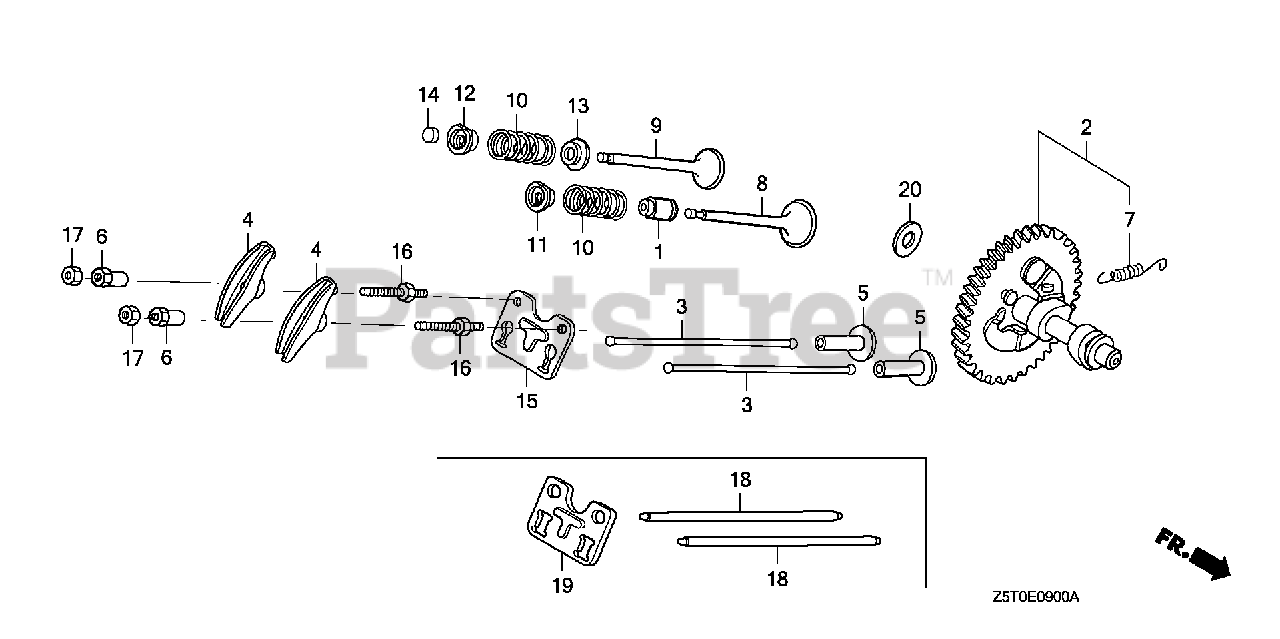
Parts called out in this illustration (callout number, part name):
1	SEAL, VALVE STEM
2	CAMSHAFT (STD)
4	ARM, VALVE ROCKER
5	LIFTER, VALVE
6	PIVOT, ROCKER ARM
8	VALVE, IN.
9	VALVE, EX.
10	SPRING, VALVE
11	RETAINER, IN. VALVE SPRING
12	RETAINER, IN. VALVE SPRING (EXHAUST SIDE)
13	SEAT, VALVE SPRING
15	GUIDE, PUSH ROD
16	BOLT, PIVOT (8MM)
17	NUT, PIVOT ADJUSTING
